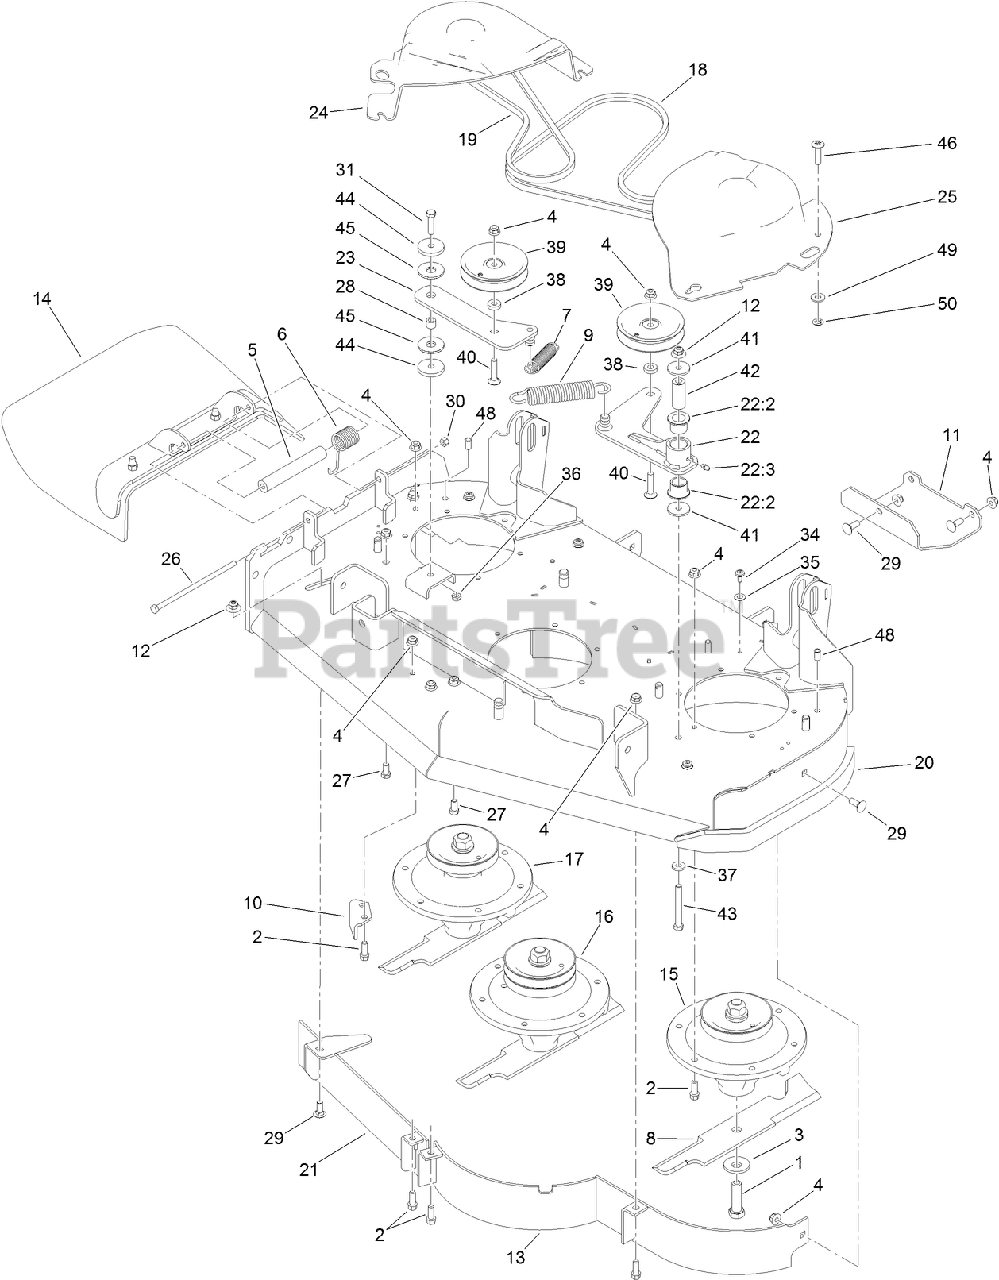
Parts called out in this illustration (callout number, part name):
1	SCREW-BLADE
2	SCREW-HWH
3	Washer-Blade Bolt, Heavy
4	NUT-HF, NI
5	SPACER
6	SPRING-TORSION
7	SPRING-EXTENSION
8	BLADE-14 INCH (HIGH SAIL)
9	SPRING-EXTENSION
10	BAFFLE-DISCHARGE
11	PLATE-SKID
12	NUT-FLANGE, NI
13	BAFFLE ASM
14	DEFLECTOR ASM
15	SPINDLE ASM
16	SPINDLE ASM
17	SPINDLE ASM
18	BELT-V
19	BELT-V
20	DECK AND DECAL ASM
21	FRONT BAFFLE ASM
22	IDLER ARM ASM
22:2	BUSHING
22:3	FITTING-LUBE, 45 DEG
23	IDLER ARM ASM
24	COVER-BELT, RH
25	COVER-BELT, LH
26	SCREW-HH
27	SCREW-HH
28	BUSHING-LEVER, LIFT
29	BOLT-CARR
30	NUT-LOCK, NI
31	SCREW-HH
34	SCREW-SHOULDER
35	WASHER-THRUST
36	NUT-LOCK, NI
37	SPACER
38	SPACER
39	PULLEY-IDLER
40	SCREW-CARR
41	WASHER
42	SPACER-PLAIN
43	SCREW-HH
44	WASHER-PLAIN
45	WASHER-FRICTION, COMPOSITE
46	SCREW-TTH
48	INSERT-NUT
49	WASHER-FLAT
50	NUT-RETAINER
